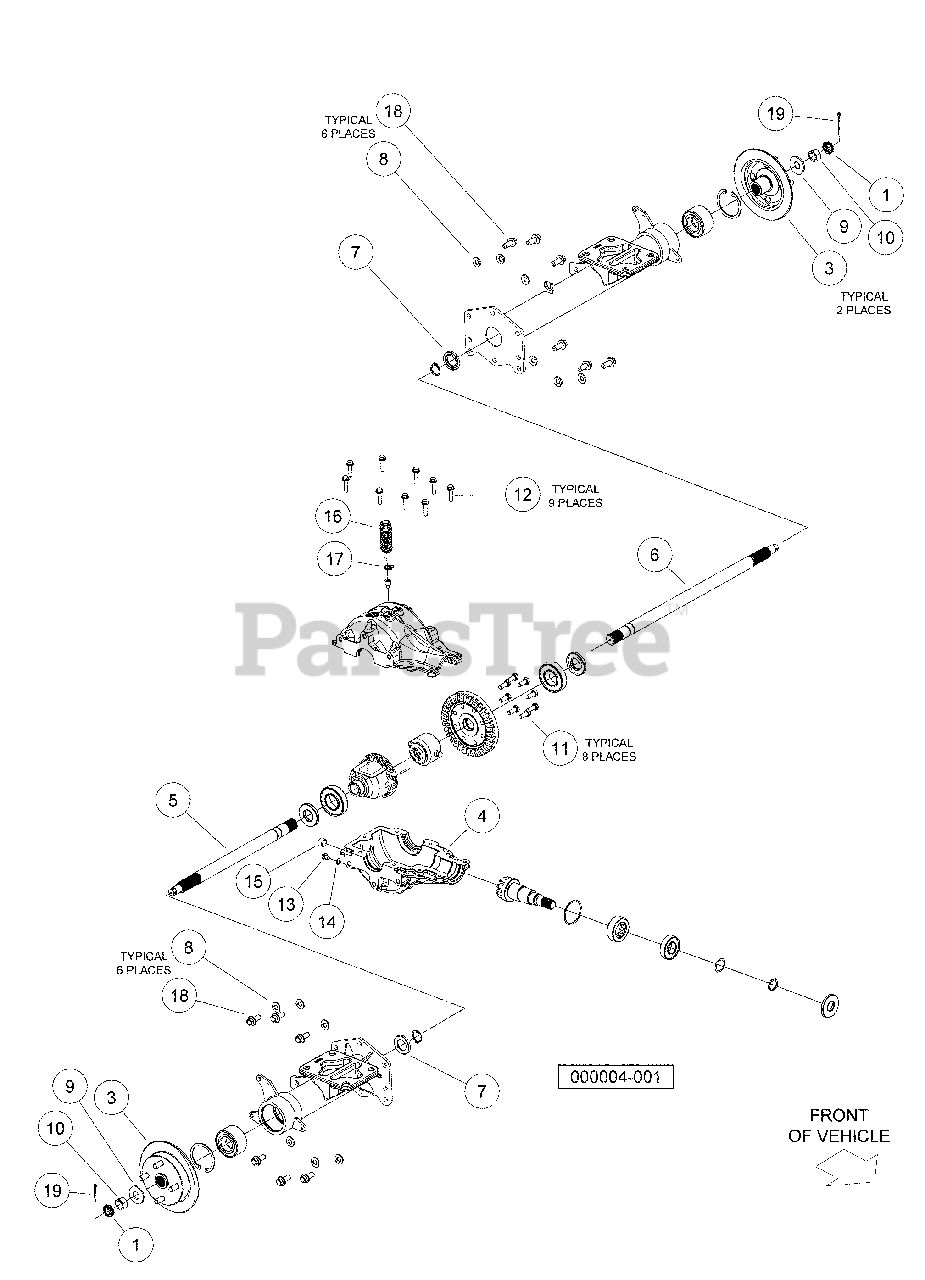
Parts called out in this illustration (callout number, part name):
1	Axle, Rear, Guard Mounts
2	Locking Cap, Nut
3	Assy, Rotor, Brake, Rear
4	Gearcase, Lower, Machined
5	Axle, Right-hand
6	Axle, Left-Hand
7	Washer,counterbored 51 X 30
8	Washer, Bellevle, 1.063 X .043
9	Washer, Belleville, 49 X 4
10	Nut, Hex, M20 X 1.5 , Modified
11	Screw, M10 X 25
12	Screw,hex Flange, M8 X 35
13	Plug,3/8-16, Hex Flange
14	Washer, .625 X .382 X .60
15	Plug, Square Skt, 1/12-14, Ptf
16	Bellows, Vent, Upper Housing
17	Clamp, Hose, Dw-9.5
18	Screw, Hex Fl, M12 X 1.75 X 30
19	Pin, Cotter, 5/32 X 1.25
